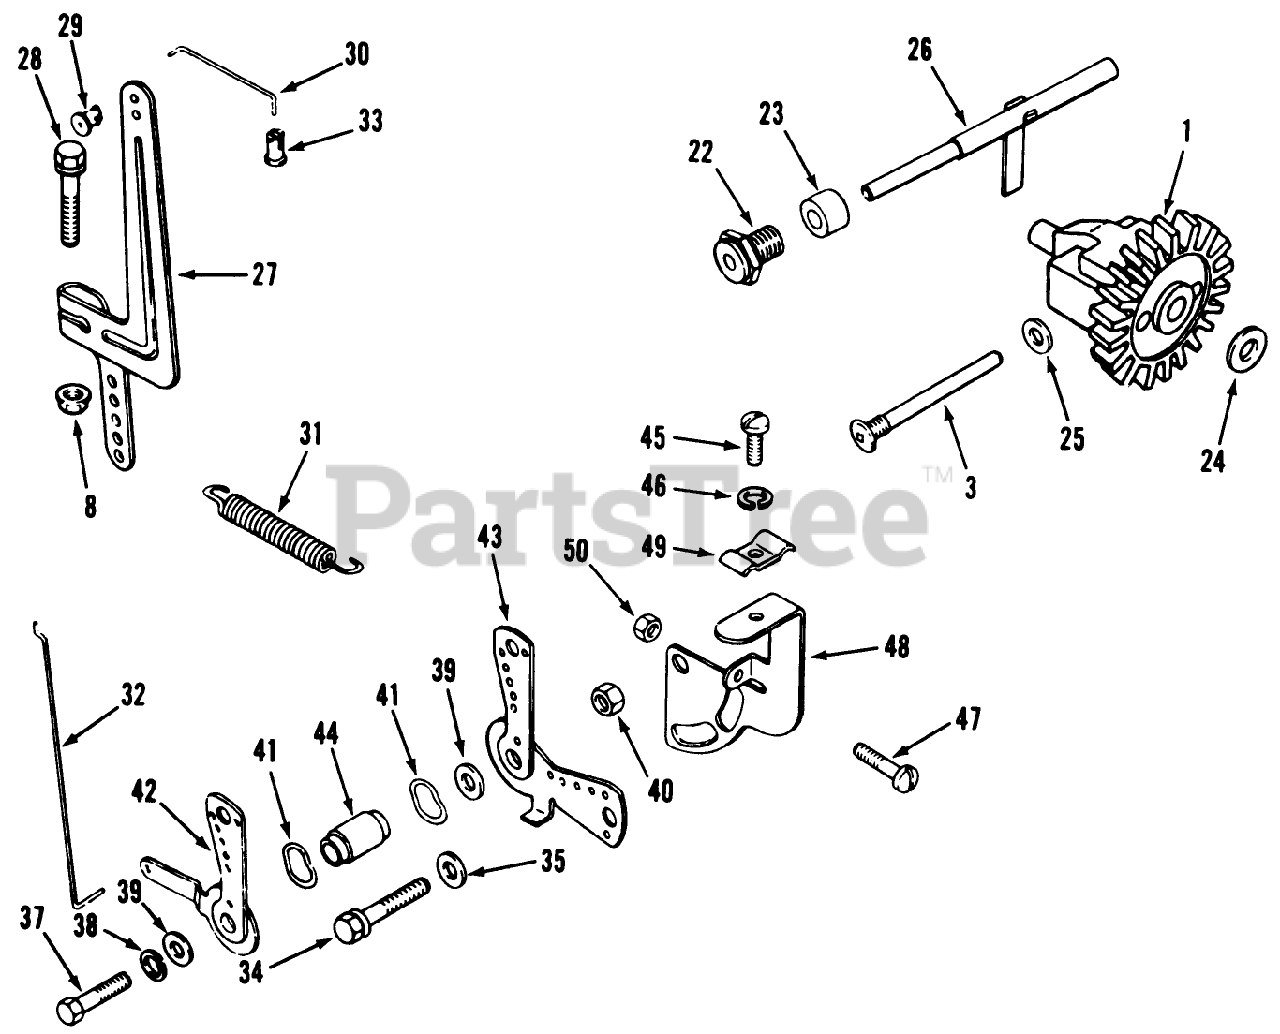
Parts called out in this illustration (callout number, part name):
1	KOHLER A-235743-5
3	KOHLER 231355
8	KOHLER X-799-1
22	KOHLER 235476
23	KOHLER X-400-80
24	KOHLER 237022
25	KOHLER 47-099-04
26	KOHLER A-235256-5
27	KOHLER 47-090-20
28	KOHLER X-776-1
29	KOHLER 47-158-07
30	KOHLER 47-079-05
31	KOHLER 47-091-01
32	KOHLER 47-079-01
33	KOHLER 25-158-09
34	KOHLER X-132-6
35	KOHLER X-25-72
37	KOHLER X-5-26
38	KOHLER X-20-1
39	KOHLER X-159-2
40	KOHLER X-76-2
41	KOHLER 275690
42	KOHLER 47-090-07
43	KOHLER 47-090-08
44	KOHLER 47-112-02
45	KOHLER X-67-51
46	KOHLER 25-468-04
47	KOHLER 232556
48	KOHLER 47-126-09
49	KOHLER 47-237-02
50	KOHLER X-72-4
